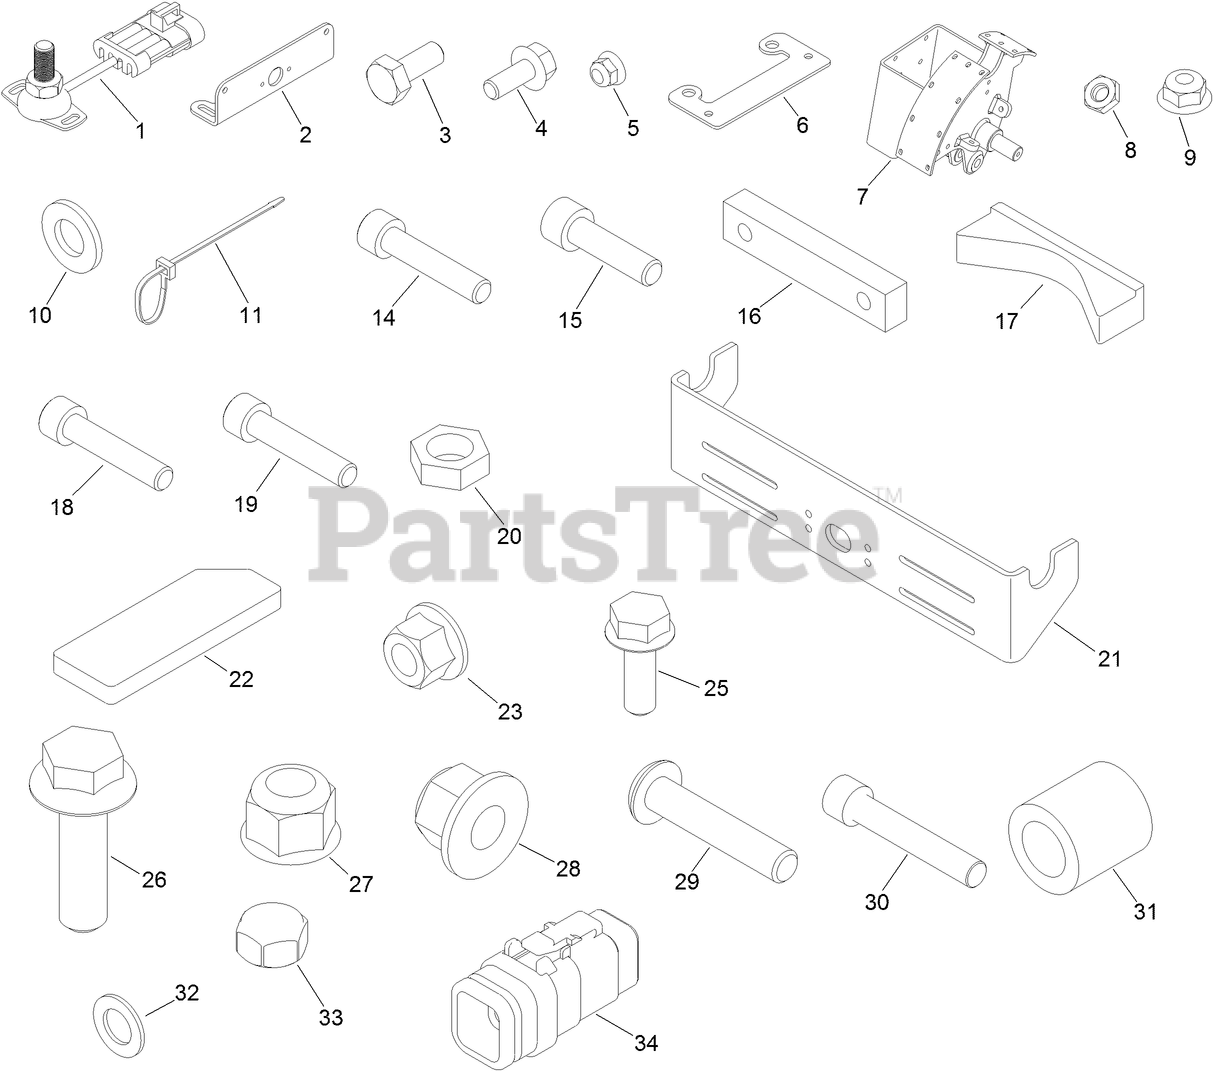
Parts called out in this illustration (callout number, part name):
1	SENSOR-ROTARY
2	BRACKET-SENSOR, ROTARY
3	SCREW-HH
4	SCREW-HHF
5	NUT-LOCK, HHF
7	UPPER CAM ASM
8	NUT-HEX
9	NUT-HHF
10	WASHER-FLAT
11	TIE-CABLE
14	SCREW-HSH
15	SCREW-HSH
16	BLOCK-ADJUSTMENT
17	BRACE-MOTOR, FLOATING
18	SCREW-HSH
19	SCREW-HSH
20	NUT-JAM
21	PLATE-MOUNT, SWITCH
22	PLATE-FLAG
23	NUT-FLANGE, NI
25	SCREW-HHF
26	SCREW-HHF
27	NUT-LOCK, NI
28	NUT-HF
29	SCREW-HSBH
30	SCREW-HSH
31	SPACER
32	WASHER
33	CAP-VALVE, ALUMINUM
